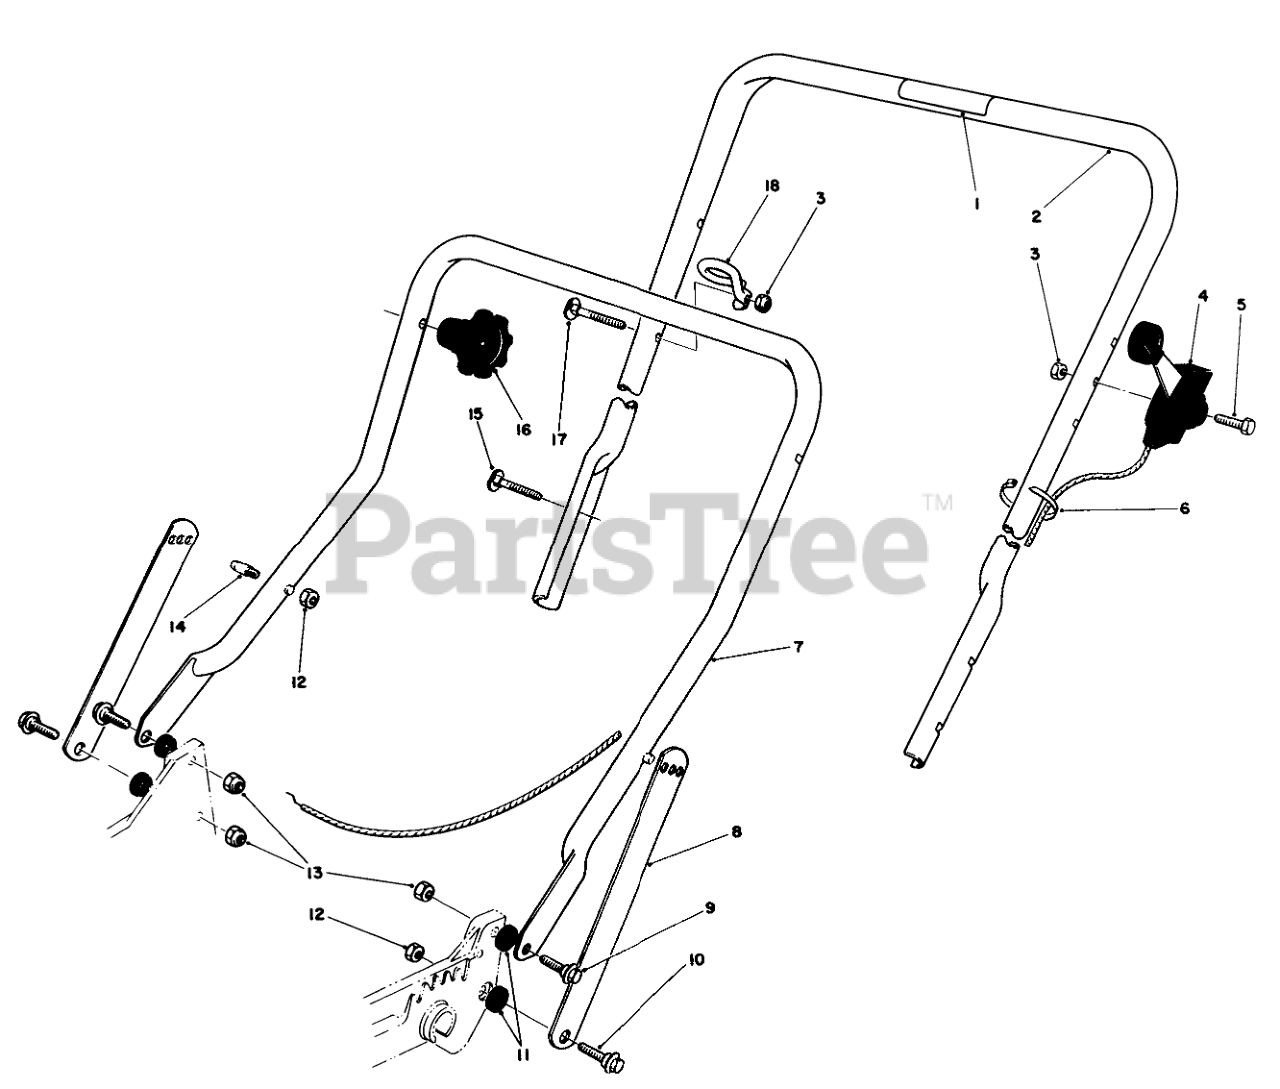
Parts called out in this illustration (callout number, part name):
1	Decal-Instructions
2	Handle-Upper (Incl. Ref. #1)
3	NUT-LOCK, NI
4	SERVICE THROTTLE CONTRO
5	SCREW-HH
6	TIE-CABLE
7	Handle-Lower
8	Handle Latch
9	SCREW-SHOULDER
10	SCREW-SHOULDER
11	SPACER
12	NUT-LOCK, NI
13	NUT-LOCK, NI
14	HANDLE PIN
15	5/16-18 X 2 HNDLE SCREW
17	HANDLE SCREW
18	Guide
